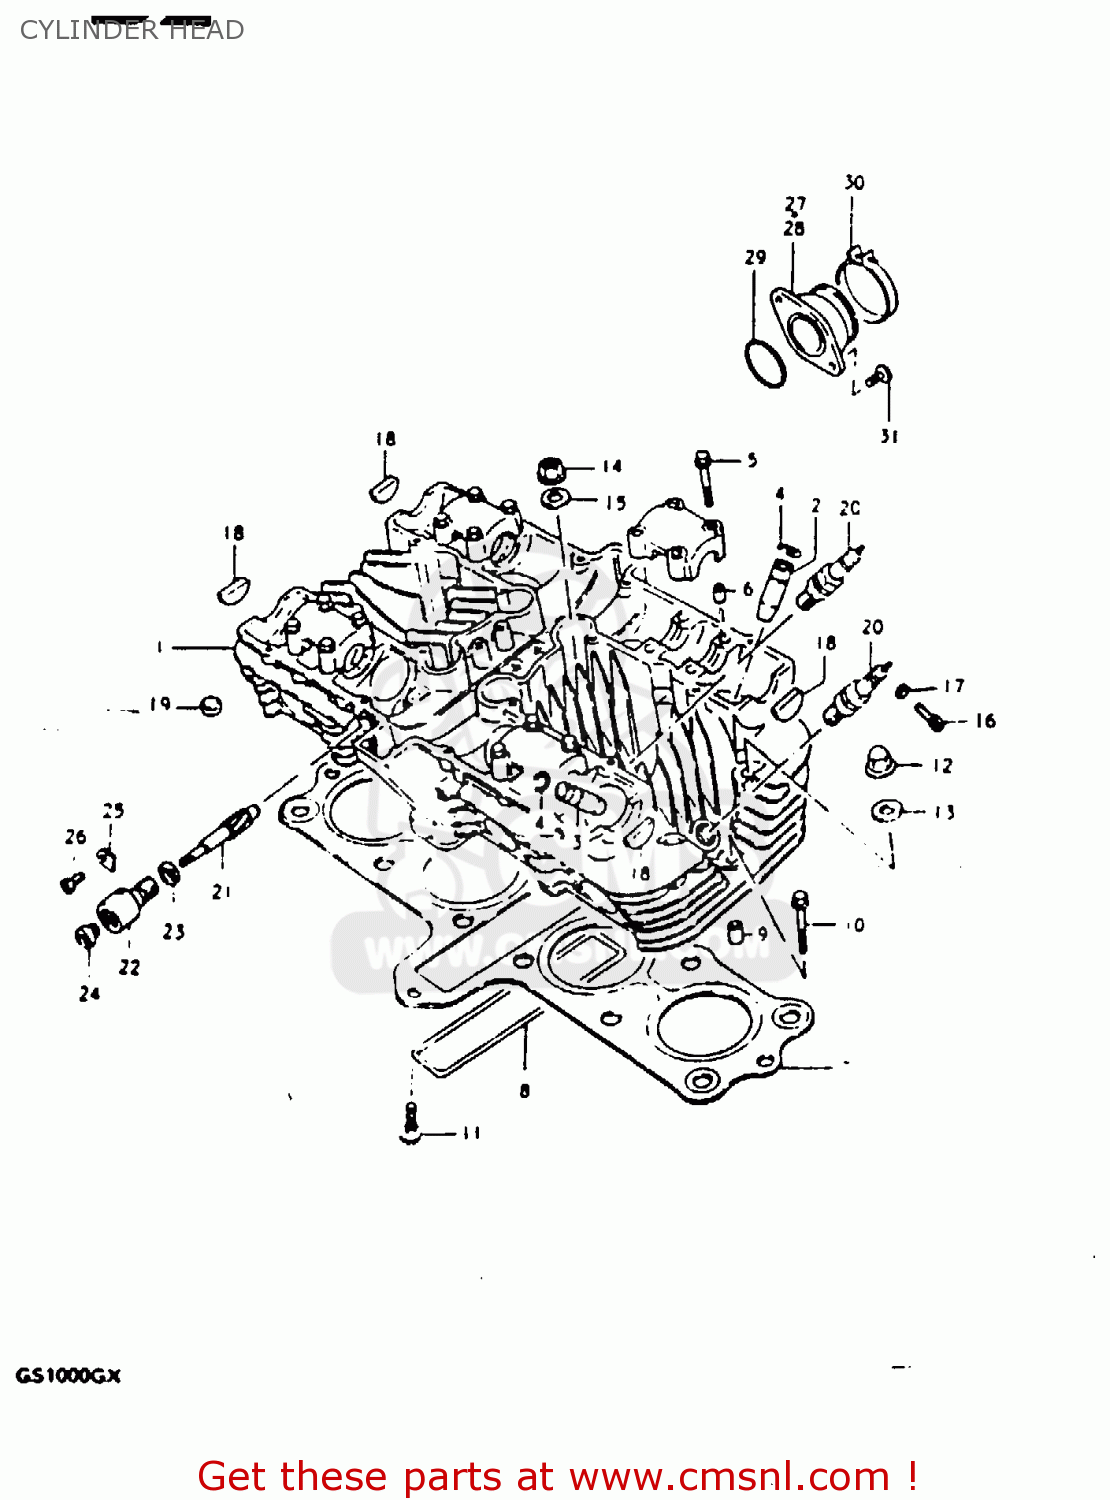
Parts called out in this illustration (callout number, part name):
1	HEAD ASSEMBLY,CYLINDER
2	GUIDE,INTAKE VALVE
3	GUIDE,EXHAUST VALVE
4	RING,SNAP
5	BOLT(6X39)
6	PIN(6.2X8X11)
7	GASKET,CYLINDER HEAD (MCA)
8	O RING(D:3,ID:26X157)
9	PIN
10	BOLT,UNDER
11	BOLT
12	NUT
13	GASKET (NAS)
14	NUT
15	WASHER(10.5X22X2.3)
16	BOLT
17	GASKET(5.3X9.3X1.2) (NAS)
18	PLUG
19	PAD
20	SPARK PLUG
21	GEAR,TACHOMETER DRIVEN
22	SLEEVE,TACHOMETER DRIVE
23	SEAL,TACHOMETER DRIVEN
24	SEAL,OIL(5X12X8)
25	PLATE,TACH DRIVE GEAR SLEEVE
26	SCREW(5X12)
27	PIPE,INTAKE,R
28	PIPE,INTAKE,L
29	O-RING (D:2.4 ID:39.7)
30	CLAMP
31	SCREW
